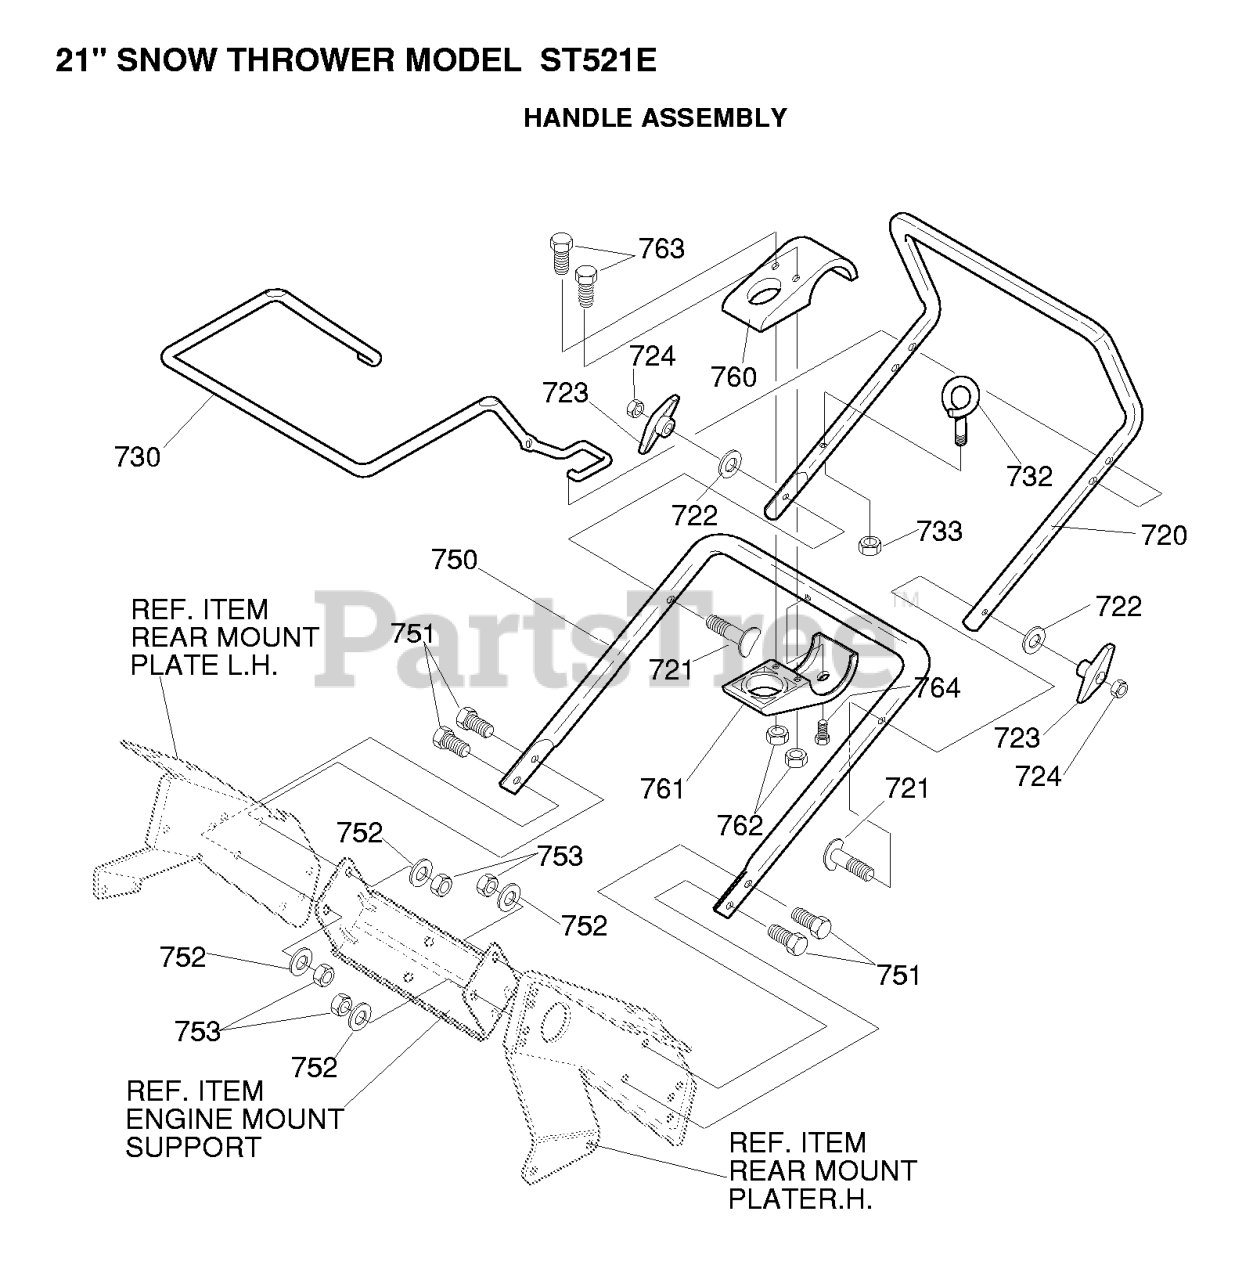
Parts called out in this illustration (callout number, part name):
720	HANDLE & FOAM ASSY
721	BOLT
723	KNOB, W/NUT
724	NUT, 5/16-18 REGHEX
730	BAR, CONTROL DRIVE .31 DIA
732	GUIDE, ROPE
733	NUT, 5/16-18 REGHEXCTRLK
750	HANDLE, LOWER
751	SCREW, 5/16-18X .75 HHC
752	WASHER, FLAT .344X .69X.
753	NUT, 5/16-18 REGHEXCTRLK
760	BRKT HALF, CHUTE CRANK
761	BRKT HALF, CHUTE CRANK
762	NUT, #10-24 HEXNYLLK
763	SCREW, #10-24X1.00
